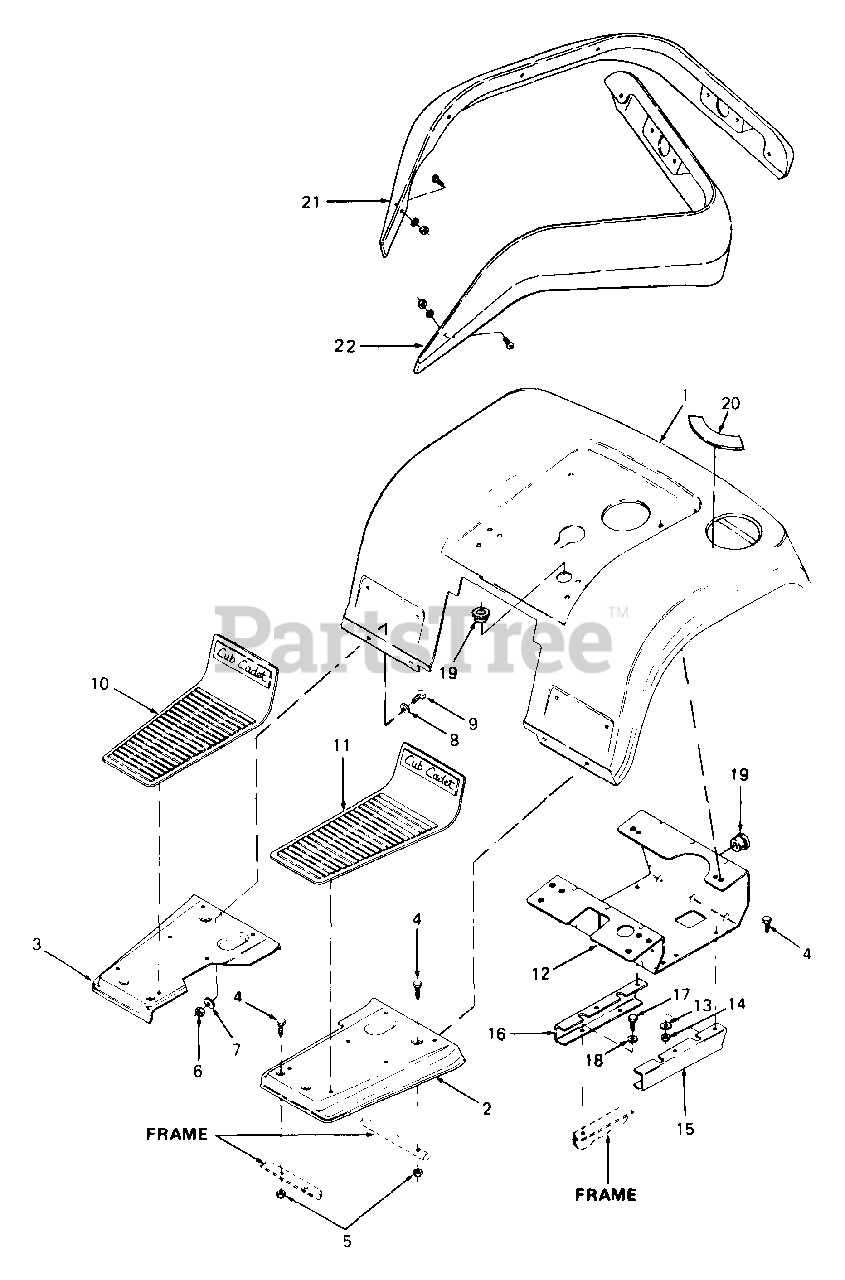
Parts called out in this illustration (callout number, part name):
5	Nut, Hex Center Lock, 5/16-18 GR5
6	Nut, Hex Patch Lock, 1/4-20
7	Washer, Bell, .265 X .75 X .062 Thk
8	Washer, Flat, .281 X .73 X .063 Thk
9	Screw, Hex Cap, 1/4-20 X .50 Lg GR5
10	Foot Pad - RH
11	Foot Pad - LH
13	Washer, Bell, .345 X .88 X .060 Thk
14	Nut, Hex, 5/16-18 GR5
15	Support Bracket, Fender - LH
16	Support Bracket, Fender - RH
17	Screw, Hex Cap, 5/16-18 X .62 Lg GR5
18	Washer, Flat, .34 X .68 X .062 Thk
19	Bushing, Snap
20	Label, Diesel Fuel Only
21	Flare, RH Fender
22	Flare, LH Fender
